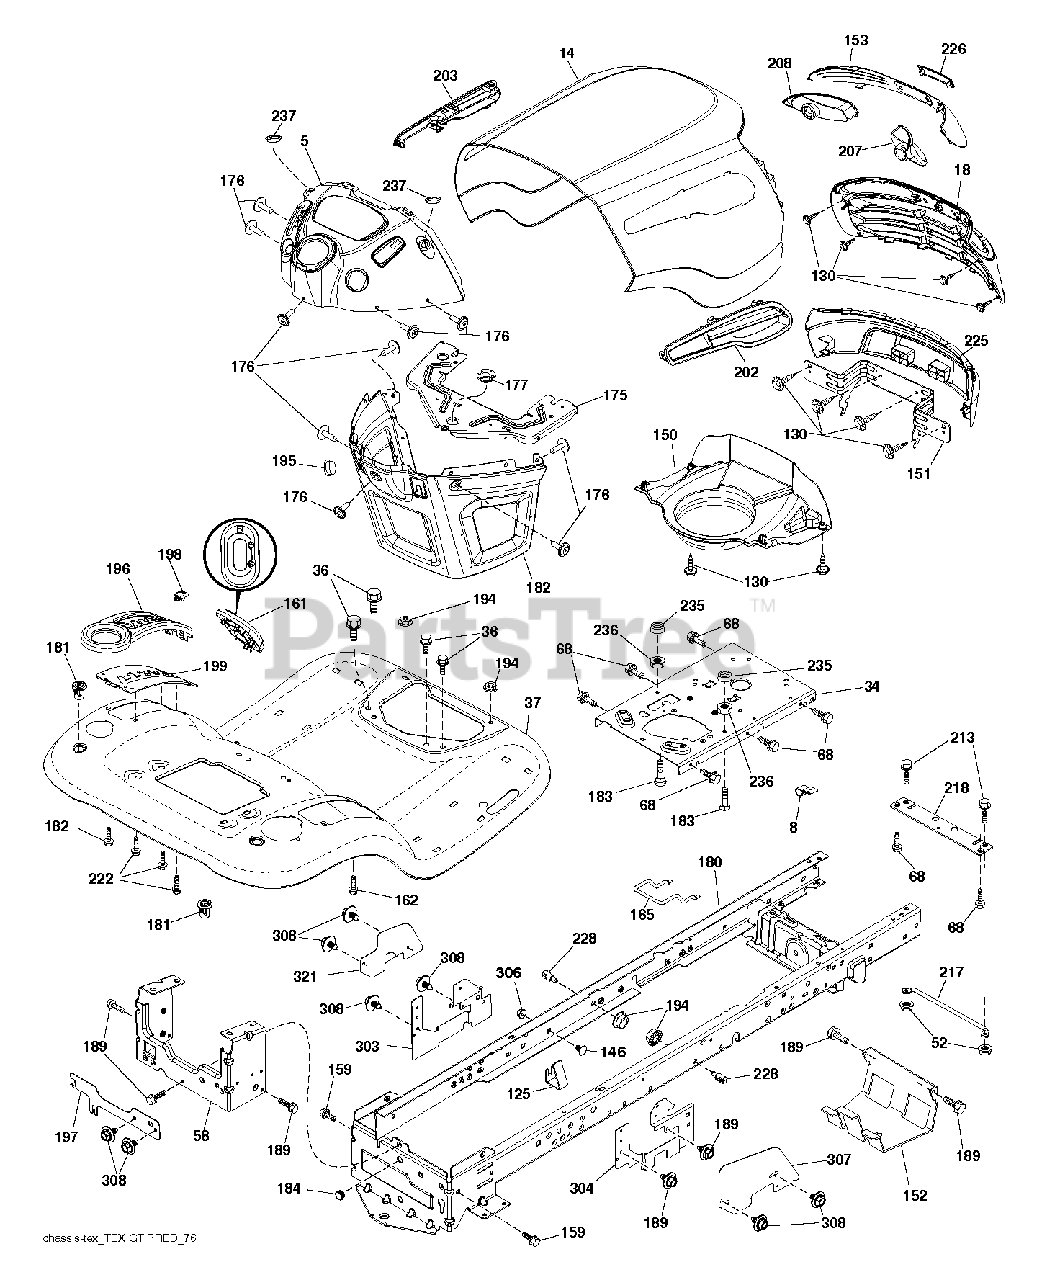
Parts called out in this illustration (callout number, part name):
8	CLIP,INSULATOR
36	SCREW 5/16"
52	LOCKNUT
58	DRAWBAR.UPPER.2PC,LRG.FENDER
125	Fuel Line Clip
130	SCREW.#10 X 0.750.BOS THREAD
146	BOLT.RDHD.SHT.SQNK.3
150	PREDATOR.YT.GT.HOOD.A
152	SHIELD BROWNING
159	SCREW, 3/8-16X3/4
161	CONSOLE.FUEL.WINDOW.STGT.BLACK
162	SCREW.HI-LO.CONSOLE
165	SUPPORT.TANK.REAR.W/TE
175	PLATE.CROSSMEMBER.HUSQ
176	SCREW.#10-24X5/8.RN.QU
177	BUSHING,STEERING
180	CHASS.WLDMNT.TLT.12GA/2PC.20"
181	FEND/FTRST.PCH.CPH.NFW
182	DASH.LOWER.COMMON.12V.ADAPTOR
183	BOLT.5/16-18X1-1/4 FULL THD
184	PLUG.DEMO.625
189	SCREW
194	NUT LOCK HEX FLANGE 5/16-18
195	PLUG.HOLE.DASH.LOWER.12V.BLK
197	SHIELD.DRWBAR.LT.RTANK.431
198	INDICATOR.DECK.LIFT.RED
199	PLATE DECK LIFT
213	BOLT
217	ROD.PIVOT.HOOD
218	X-PIECE.HOOD.STOP.NON/
222	SCREW.1/4-20X5/8
228	STUD.FASTNER.W/ANTI-ROTATE
235	SPACER FENDER
236	NUT.CENTERLOCK.5/16-
237	PLUG.MOUNT.CARGO.BLK
306	NUT LOCK FLG 3/8-16 UNC
308	BOLT, 5/16-18 X 1 3/4
321	SHIELD.UPPER.LH.GT
